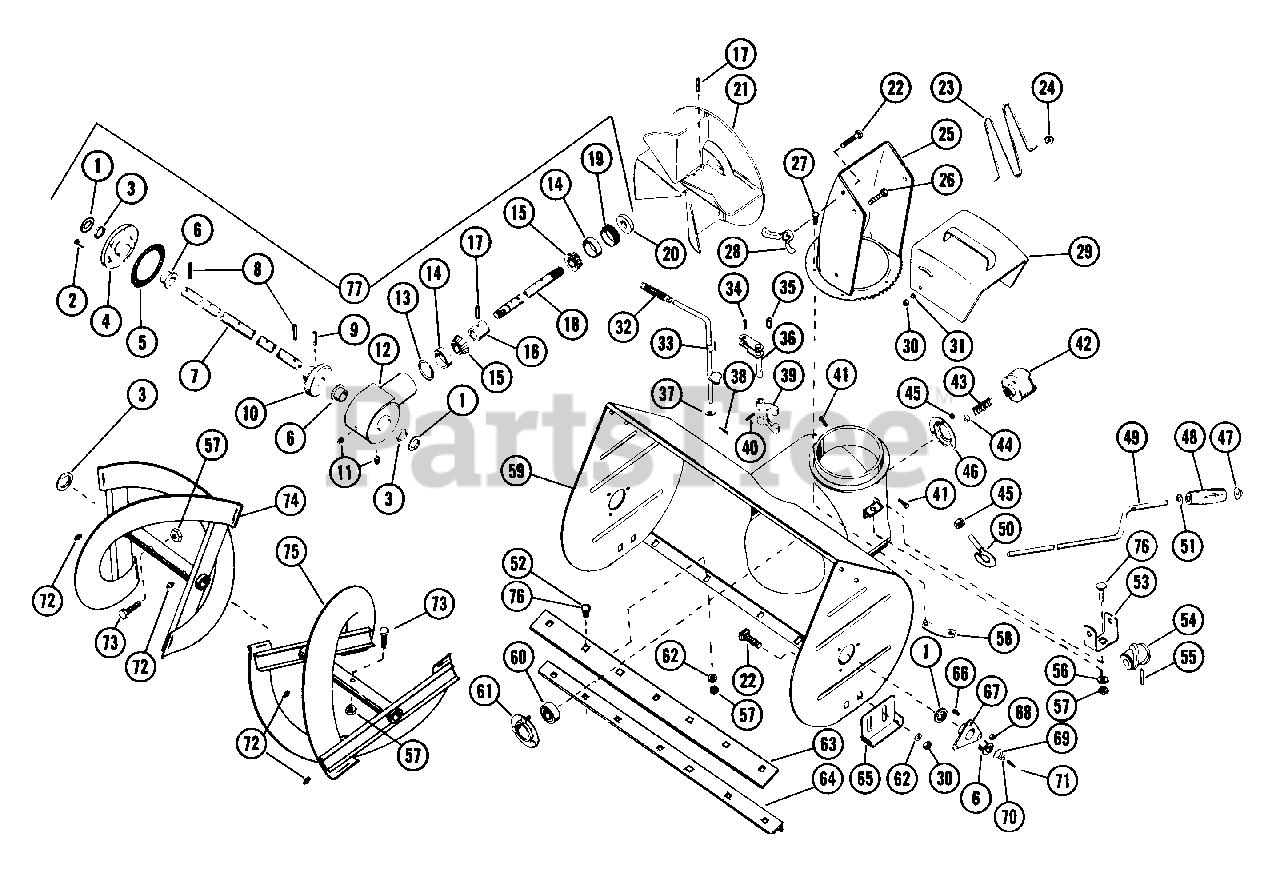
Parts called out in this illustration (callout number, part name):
1	WSHR-FL-STL 1.010X1.505X.062PL
2	BLT-SERHFWH .25-20X.75 PL
3	SEAL 1.000X1.312X.150
4	GEAR CASE FLANGE
6	BSHG-FLG 1.000X1.12X.62X1.50BR
7	FRONT GEAR SHAFT
8	PIN-ROLL .188X1.50
9	PIN-ROLL .313X1.38
10	HELICON GEAR - 41 TOOTH
11	PIPE PLUG
12	CASE, GEAR - C.I.
13	RG-RTNG INT 1.781 HSG X.062
14	BRG-CUP 1.781X.475
15	BRG-CONE .750X.61
16	BEARING SPACER
17	PIN-ROLL .250X1.25
18	HELICON PINION SHAFT
19	ADJUSTMENT PLUG
20	SEAL .750X1.499X.225
22	BLT-RDHDSQNK .38-16X.75 SHT PL
23	SAFETY WIRE
24	FASTENER
25	DISCHARGE CHUTE
26	BLT-HEX .38-16X.75 PL GR2
27	SCR-TAP 10-24X.375 CRPH 1A
28	WING NUT
29	DEFLECTOR CHUTE
30	NUT-LK-CTR .375-16 GR A PL
31	WSHR-LK .375X.115 HVY PL
33	FORK CAM
34	PIN-ROLL .313X1.25
36	FORK SHAFT
37	WAVE WASHER .406X.750X.063FH
38	PIN-COTR .12X1.0 PL
39	CLUTCH FORK
40	PIN-ROLL .188X1.00
41	BLT-SCRHFWH .38-16X.75 PL
42	JAW CLUTCH
43	SG-COMP .105X1.35X1.984
44	WSHR-FL-STL .755X1.375X.062 PL
45	NUT-LK-CTR .250-20 PL
46	BEARING FLANGE
47	CAP, 3/8 ROD YWZC
50	ROD HANGER EYEBOLT
51	WSHR-FL-STL .382X.812X.023 PL
52	BLT-RDHDSQNK .312-18X.62 PL
53	WORM CLEVIS
54	WORM GEAR
55	PIN-ROLL .125X.75
56	WSHR-FL-STL.312X.734X.065PL
57	NUT-LK .312-18 GR A PL
58	CHUTE CLAMP
59	BLOWER HOUSING
60	BRG-BALL .750X1.750X.50
61	BEARING FLANGE
62	WSHR-FL-STL .38X.875X.083 PL
63	SCRAPER BLADE
63	SCRAPER BLADE 24"
64	REINFORCEMENT ANGLE
65	RUNNER
66	SCR-SLTR-SERNK .25-20X.62 PL
67	BEARING SUPPORT
68	NUT-LK-FLG .250-20 PL
69	WSHR-FL-STL .511X1.441X.125 PL
70	WSHR-LK .500X.151 HVY PL
71	BLT-HEX .50-13X1.00 PL GR2
72	HYDRAULIC DRIVE FITTING
73	SHEAR BOLT YWZC
74	RAKE, R.H. - 32"
74	RAKE, RIGHT-24"(1ID X 15.88OD)
75	RAKE, L.H. - 32"
75	RAKE, LEFT-24"(1"ID X 15.88OD)
76	BLT-RDHDSQNK .31-18X.75 GR5 PL
77	GEAR CASE - C.I.
77	GEAR CASE ASSEMBLY
